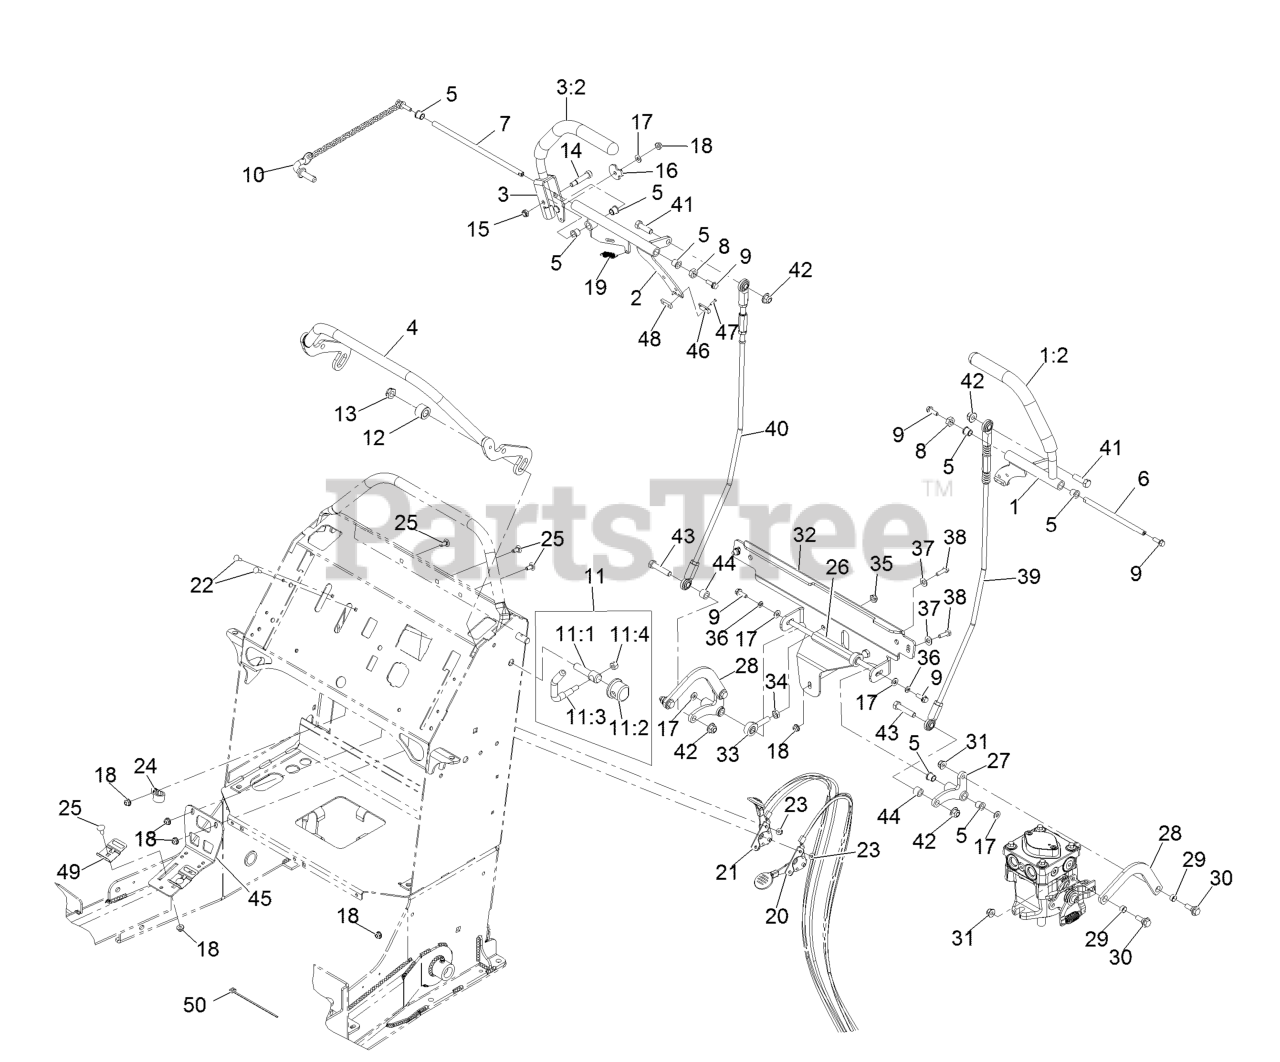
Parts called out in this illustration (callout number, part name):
1	LEVER ASM, LH
1:2	GRIP-HANDLE, CONTROL
2	MOTION CONTROL ASM-RH
3	LEVER ASM, RH
3:2	GRIP-HANDLE, CONTROL
4	TUBE ASM, FRONT SPEED CONTROL
5	BEARING
6	SHAFT-PIVOT, MOTION CONTROL
7	SHAFT-PIVOT, MOTION CONTROL
8	SPACER-SHAFT, DRIVE LEVER
9	SCREW-HHF
10	HOC PIN ASM
11	LEVER ASM
11:1	SCREW-LOCK
11:2	CAP-LOCK
11:4	NUT-LOCK, NI
12	SPACER-CLAMP
13	NUT-HEX
14	SCREW-HSH
15	NUT-LOCK, NI
16	CAM-LEVER
17	WASHER-FLAT
19	SPRING-EXTENSION
20	CONTROL-THROTTLE
21	CONTROL-CHOKE
22	BOLT-CARR
23	NUT-LOCK, FLANGE
24	CLAMP-CABLE
25	SCREW-CARR
26	SHAFT-BELLCRANK PIVOT
27	BELLCRANK-CONTROL, MOTION
28	LINK-BELLCRANK, PUMP
29	BUSHING-SLEEVE
30	SCREW-SHOULDER
31	NUT-HF, NI
32	BRACKET-BELLCRANK
33	BALLJOINT
34	NUT-HJ
35	NUT-HEX
36	SCREW-HH
37	WASHER-PLAIN
38	SCREW-HH
39	LINKAGE-TRACKING CONTROL,LH
40	LINKAGE-TRACKING CONTROL,RH
41	SCREW-HH
42	NUT-HF, NI
43	SCREW-HH
44	SPACER-WHEEL
45	BRACKET, REED SWITCH
46	ACTUATOR-SWITCH, REED
47	SCREW-HH
48	PLATE-TAPPED
49	CLAMP, REED SWITCH
50	TIE-CABLE
